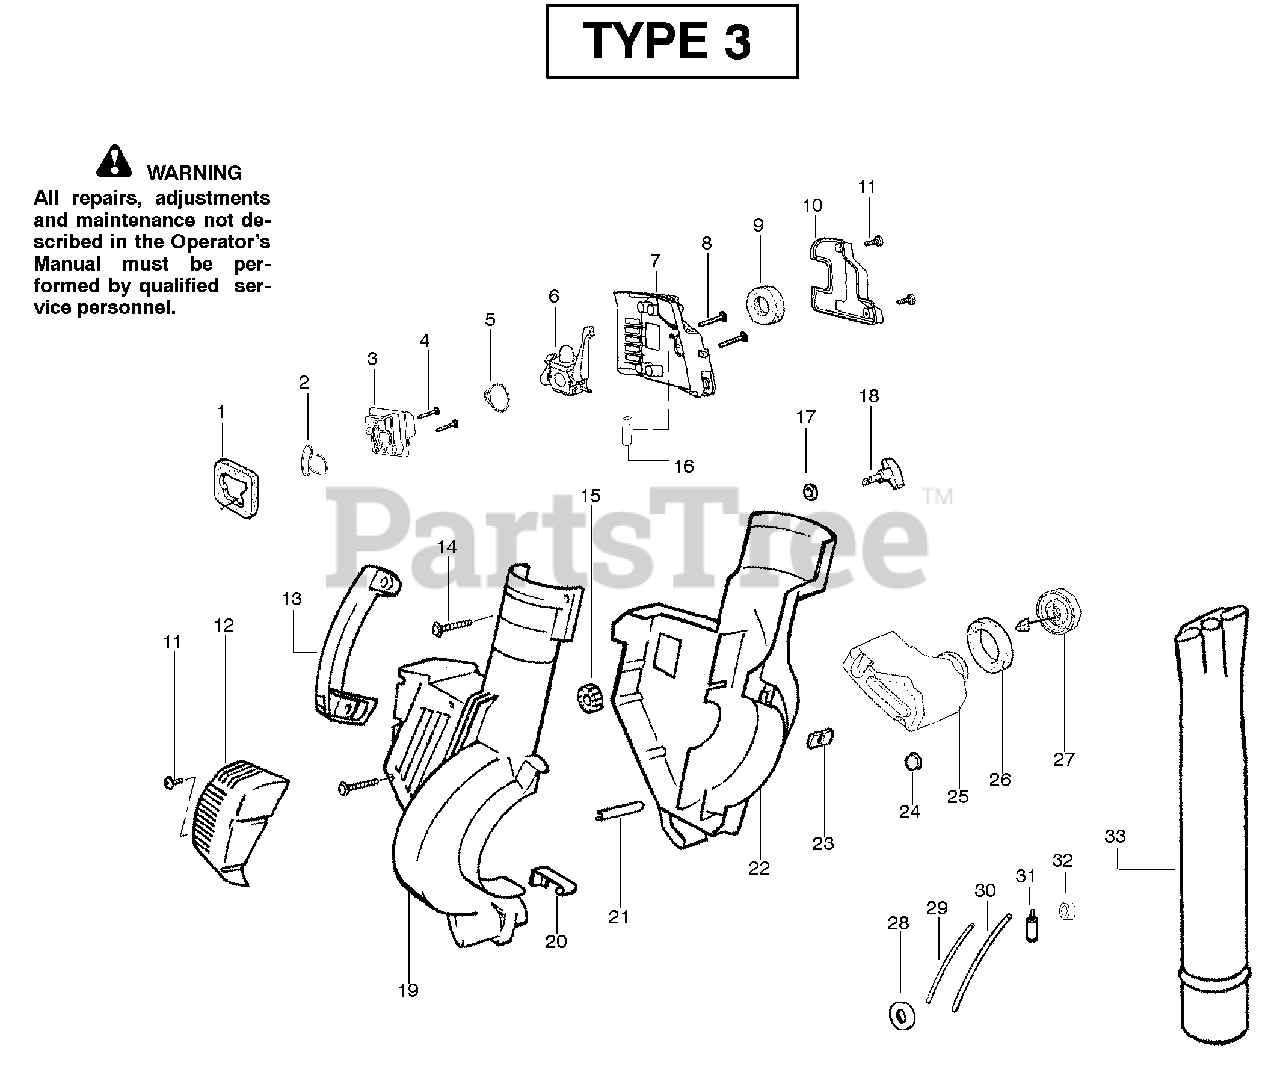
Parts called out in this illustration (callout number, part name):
1	Air Dam (kit)
2	Gasket-Adapter (kit)
3	Carburetor Adaptor
5	Gasket-Carburetor (kit)
6	Kit-Carb Ass'y. (C1Q-W11)
6	Kit-Carb Ass'y. (C1Q-W11C)
6	Kit-Carb Ass'y. (WT-606)
8	Screw-Carb.
9	Filter-Air
10	Cover-Air Filter
12	Guard-Muffler
15	Isolator
16	Foam 25.4mm (kit)
18	Knob-Blower
19	Housing-Right
20	Spring-Cover Latch
21	Guide-Starter Rope
22	Housing-Left
24	Isolator-Crankcase
25	Assy-Fuel Tank
26	Gasket-Fuel Tank
27	Fuel Cap w/Retainer
28	Grommet-Shroud
29	Kit-Line Carb/Purge
30	Kit-Line Tank/Purge
31	Assy-Fuel Pick-up
32	Grommet-Fuel line (kit)
33	Tube-Blower
